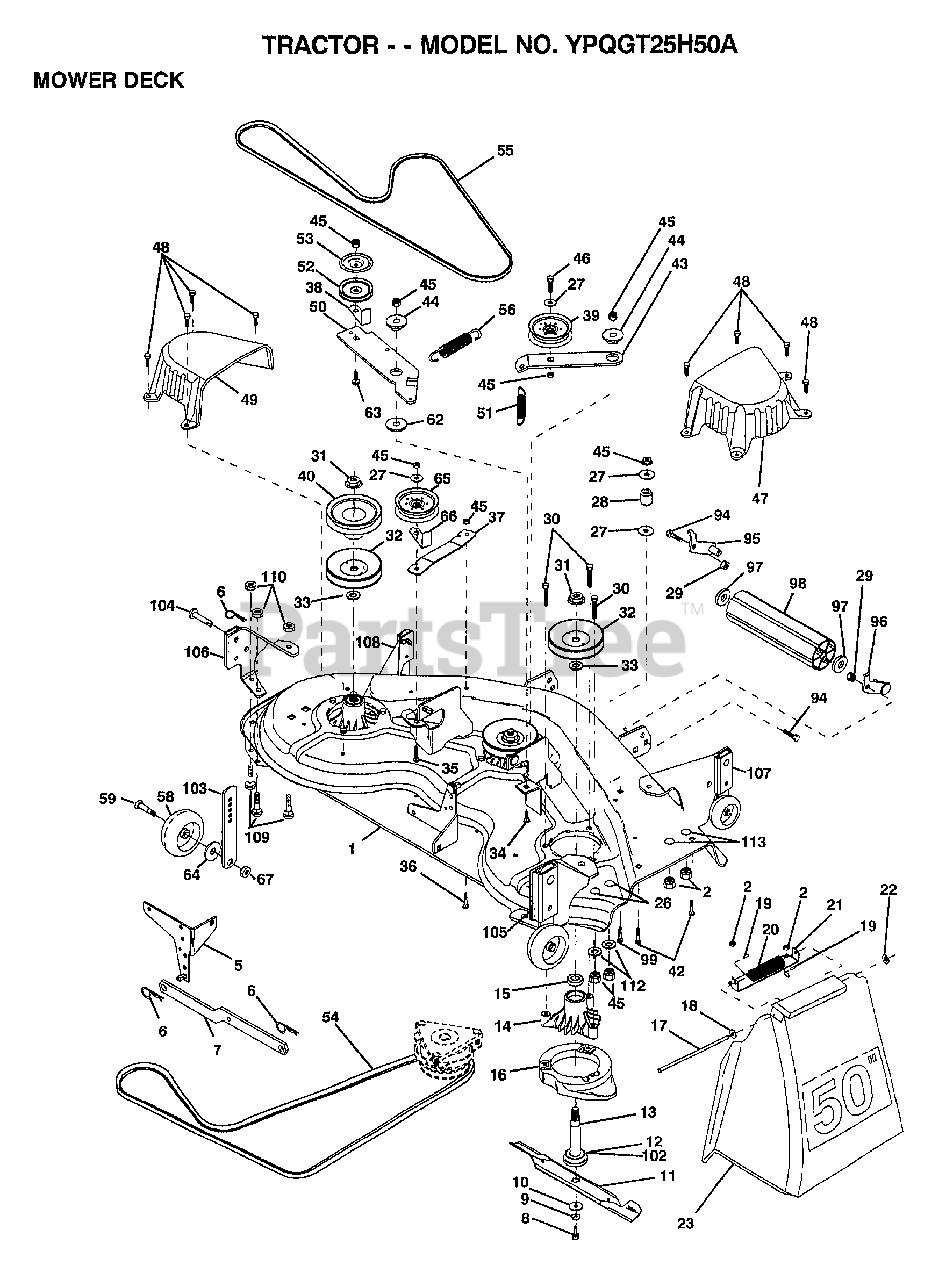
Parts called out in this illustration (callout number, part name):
1	"DECK ASM-50"""
5	BRKT.ASM.SW.44/50
8	BLADE BOLT
10	WASHER.HARD.BLADE
11	"BLADE.50"" HD"
12	BEARING.BALL
13	SHAFT.ASM.W/BRNG
14	HOUSING.MAND.44.V
15	BEARING
16	STRIPPER RND MWR
17	ROD-HINGE T
18	WASHER
19	CAP-SLEEVE LT
20	SPRING TORSION
21	BRKT DEFLECTOR
22	NUT PUSH M
23	DEFLECTOR
25	WASHER M
26	BOLT
27	WASHER
29	NUT
30	"SCREW-THD ROLL,WA"
32	PULLEY.MANDREL.42
33	WASHER
34	BOLT.3/8-14X1.25
35	BOLT
36	BOLT D
37	STIFFENER.ARM.IDL
38	"KEEPER-BELT,IDLER"
39	FLAT IDLER PULLEY
40	"PULLEY.DRIVEN.44"""
42	BOLT
43	"ARM.IDLER.SEC.44"""
44	SPACER.RETAINER.MOWER
47	"COVER.MAND.RH.44"""
48	SCREW.1/4-20X5/8
49	COVER.MANDREL.LH
50	ARM.IDLER.PRIMARY
51	"SPRING.SEC.44""VEN"
52	PULLEY.IDLER.VGRO
53	SHIELD.IDLER.44.V
54	BELT V PRIM 50
55	BELT-V.SEC.46.KEL
56	SPRING.EXT.DECK.
58	WHEEL GAGE DONUT
59	BOLT.SHOULDER
62	HARDENED WASHER
63	BOLT.3/8-16X1.50
64	WASHER
65	PULLEY IDELR FLAT
66	"KEEPER-BELT,IDLER"
67	LOCKNUT
94	BOLT
97	WASHER
99	BOLT
102	WASHER.FELT.
104	RIVET-PAN HEAD
105	"BRKT ASM GA,WH,RR"
106	"BRKT ASM GA,WH,RR"
107	"BRKT ASM,GA,WH,FR"
108	"BRKT ASM,GA,WH,FR"
109	BOLT.CARRIAGE
112	WASHER
